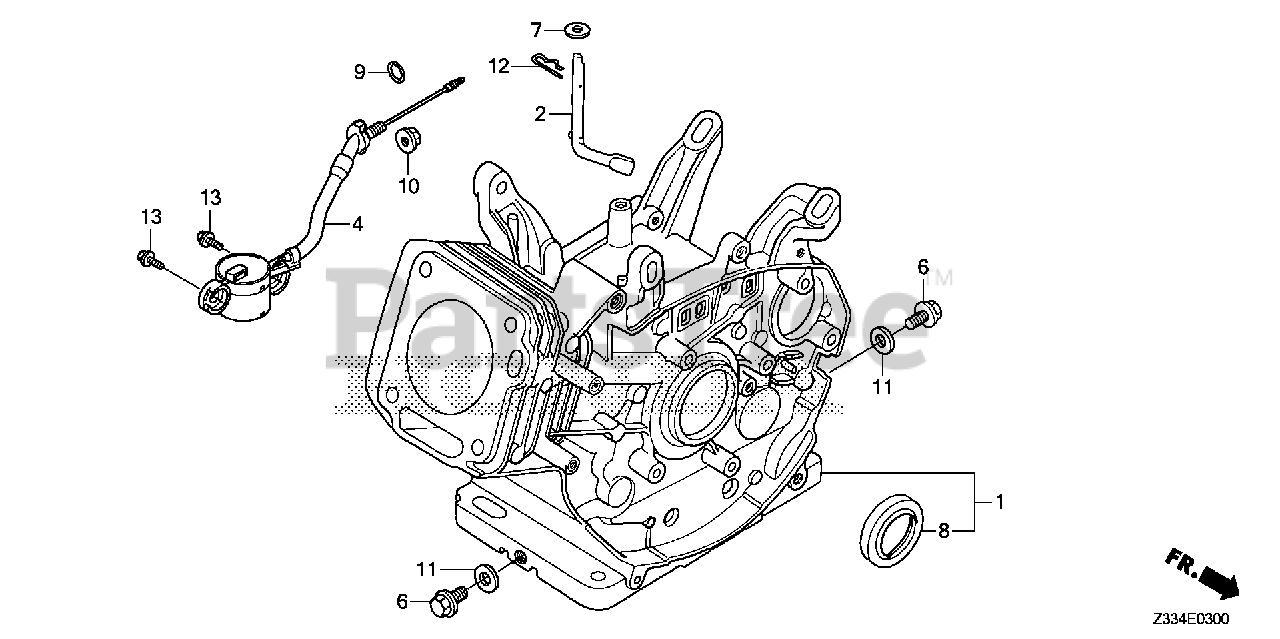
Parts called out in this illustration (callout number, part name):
1	CYLINDER ASSY.
2	SHAFT, GOVERNOR ARM
4	SWITCH ASSY., OIL LEVEL
6	BOLT, DRAIN PLUG (12X15)
7	WASHER (8.2X17X0.8)
8	OIL SEAL (30X46X8) (NOK ASIA)
9	O-RING (13.5X1.5) (ARAI)
9	O-RING (14MM) (NOK)
10	NUT, FLANGE (10MM)
11	WASHER, DRAIN PLUG (12MM)
12	PIN, LOCK (10MM)
13	BOLT, FLANGE (6X12)
